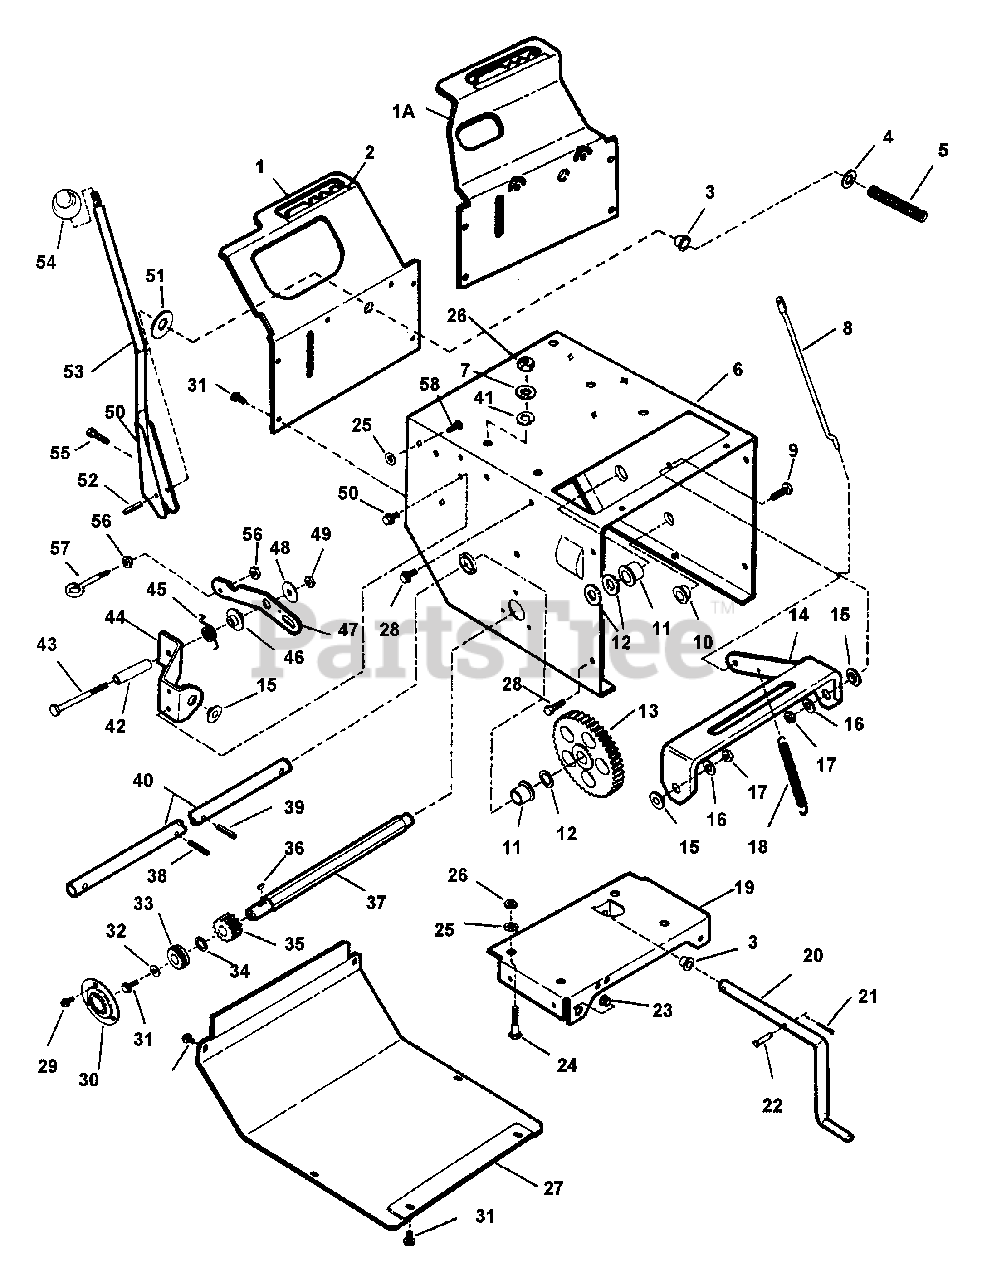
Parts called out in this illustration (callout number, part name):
1	COVER, Rear Frame
1A	COVER, Rear Frame
2	DECAL, Direction Control
3	BUSHING, 1/2" Nylon
4	WASHER, 1/2" Flat
5	SPRING, Shift
7	WASHER, 5/16" Flat
8	ROD, Clutch
9	SCREW, 3/8-16 x 1" Hex Head Cap, Grade 5
10	BEARING
11	BUSHING
12	WASHER, 3/4" Flat
13	GEAR, Axle Shaft
14	BRACKET, Clutch
15	BUSHING
16	WASHER, 3/8" Flat
17	NUT, 3/8-16 Hex Center Lock, Grade B or 5
18	SPRING, Clutch
19	SUPPORT, Engine
20	ROD, Shift
21	PIN, 1/16 x 1/2" Cotter
22	PIN, 3/16 x 7/8" Clevis
23	BUSHING, 3/8" Plastic
24	SCREW, 5/16-18 x 1" Hex Head Cap, Grade 5
25	RETAINER, 5/16" Bolt
26	NUT, 5/16-18 Hex, Grade 5
27	COVER, Bottom Frame
28	SCREW, 5/16-18 x 1/2" Hex Washer Self-Tap
29	SCREW, #10-32 x 1/4" Hex Washer Self-Tap
30	RETAINER, Bearing
31	SCREW, 1/4-20 x 1/2" Hex Washer Self-Tap
32	WASHER, 1/4" Flat
33	BEARING, Ball
34	WASHER, 1/2" Shim
35	GEAR, Pinion
36	KEY, 3/32 x 1/2 Woodruff (#304)
37	SHAFT, Hex
38	PIN, 1/4 x 1-1/4" Roll
39	PIN, 1/4 x 1" Roll
40	AXLE, Shaft
41	WASHER, 5/16" Split Lock
43	SCREW, 5/16-18 x 3" Hex Head Cap, Grade 5
44	BRACKET
45	SPRING
46	BUSHING
47	LEVER
48	WASHER, 5/16" Flat
49	NUT, 5/16-18 Hex Center Lock, Grade B
50	HUB
51	WASHER, Thrust
52	PIN, 3/16 x 1" Roll
53	SHIFTER
54	KNOB, Shifter
55	SCREW, #10-32 x 5/8" Hex Washer Self-Tap
56	NUT, 1/4-20 Hex Flange Lock
57	BOLT, 1/4-20 Eye
58	BOLT, 5/16-18 x 5/8" Short Neck Carriage, Grade 5
